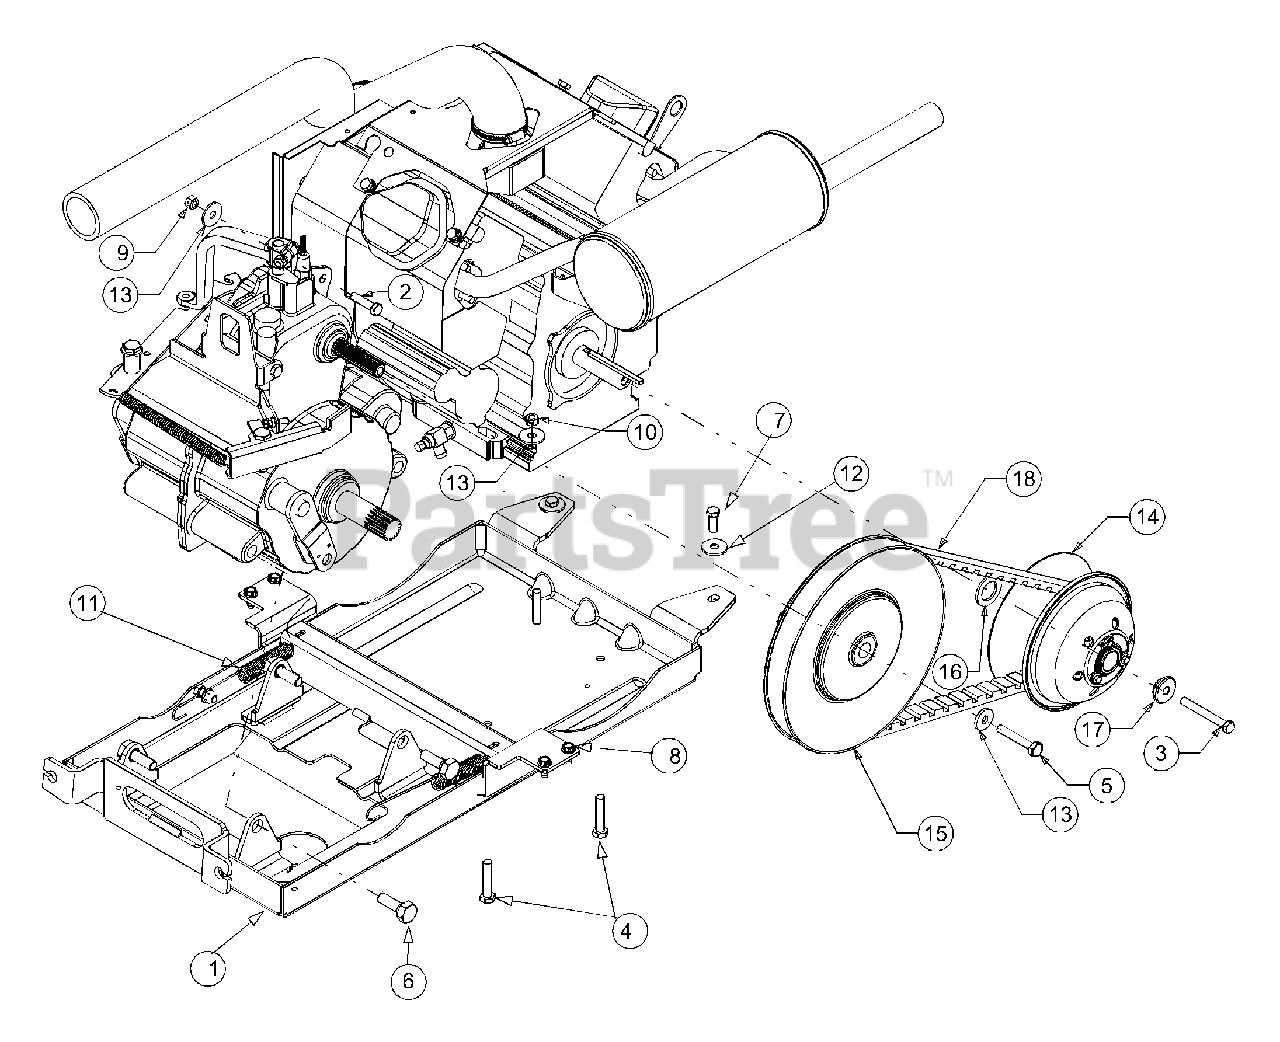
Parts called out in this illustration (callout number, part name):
1	Frame Assembly, Engine/Trans. Support
2	Hex Screw, 3/8-16 x 1.5, Gr5
3	Hex Screw, 3/8-24 x 3, Gr5
4	Hex Screw, M10-1.25 x .50, Gr8
5	Hex Screw, M10-1.5 x 60mm, Gr8
6	Hex Screw, M16-2 x 40mm
7	Hex Screw, 3/8-16 x 2.25, Gr5
8	Hex Screw, 5/16-18 x.75
9	Nut, Hex Lock, 3/8-16
10	Nut, Nylon Lock, M10-1.25
11	Spring, Extension, .795 x 5.42
12	Washer, Flat, .411 x 1.25 x .10
13	Washer, Flat, .395 x 1.12 x .14
14	Clutch Assembly, Engine
15	Clutch Assembly, Transmission
16	Washer, 1.03 x 1.625 x .12
17	Spacer, Drive, .39 ID x 1.00 OD
18	V-type Belt, Cogged, 1.19
